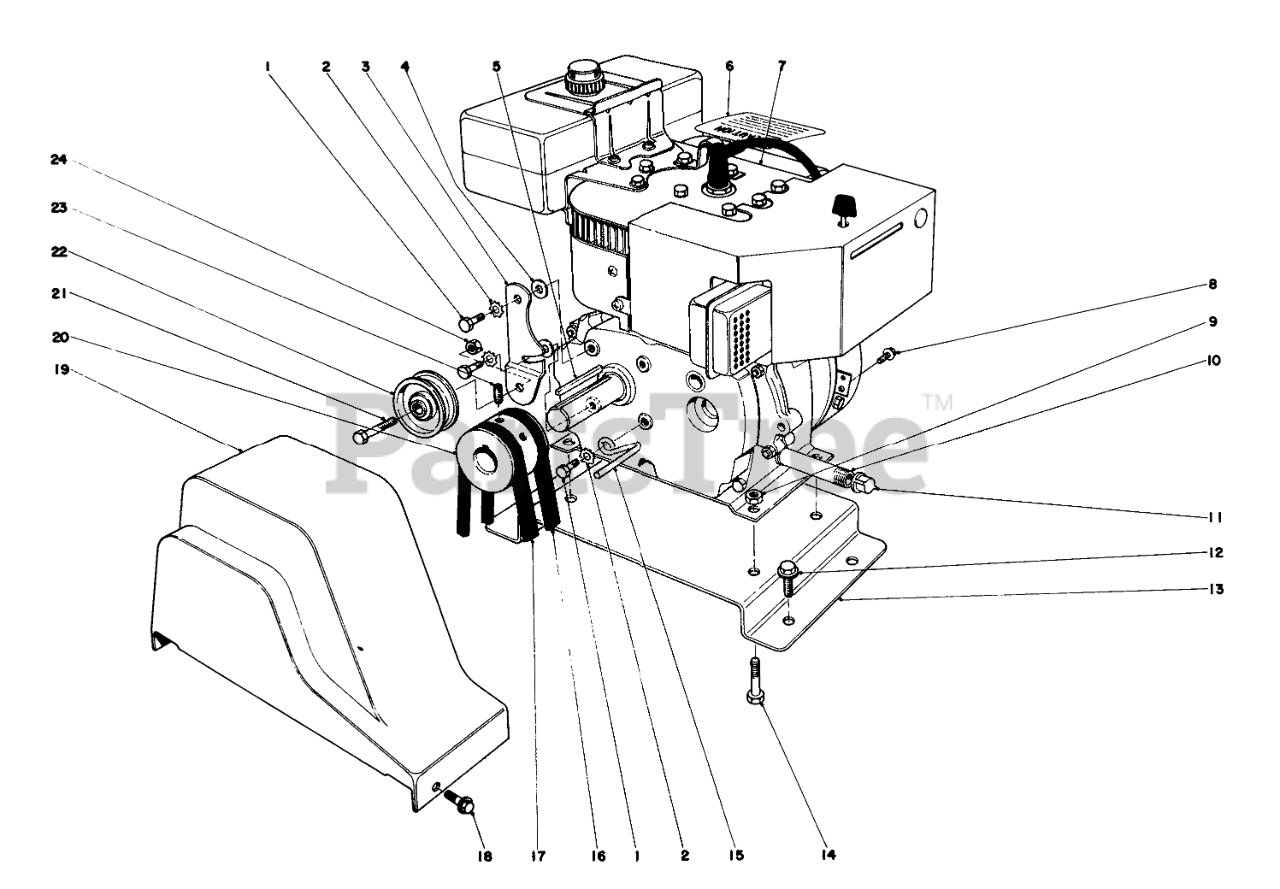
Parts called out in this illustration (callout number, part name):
1	SCREW-HH
2	WASHER-LOCK
3	ENGINE IDLER ARM
4	WASHER-PLAIN
6	Engine
7	Decal Instruction
8	SCREW
9	NUT-LOCK, CONE
10	NIPPLE-PIPE
11	CAP-PIPE
12	SCREW-HHFTF
13	ENG MTG PLATE R
14	SCREW-HH
15	BELT RETAINER
16	V-BELT
17	V-BELT
18	SCREW-HWH
19	BELT GUARD
20	ENGINE PULLEY
21	SCREW-HH
22	PULLEY-IDLER
23	Screw-Set
24	NUT-HEX
